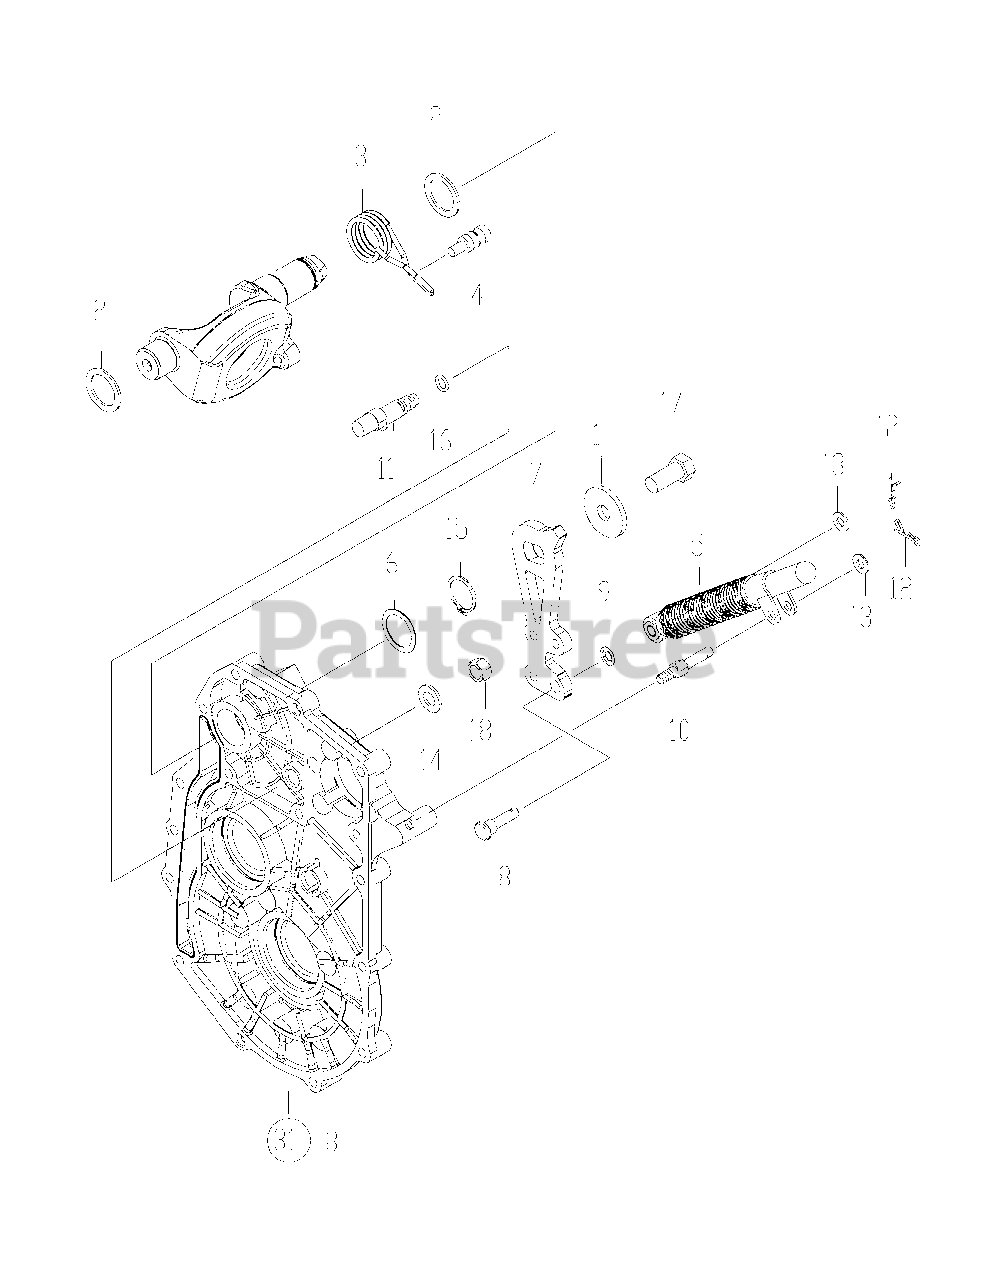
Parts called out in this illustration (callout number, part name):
1	WASHER, 44X14X4.5
2	WASHER, 28X38X2
3	SPRING, CENTERING
5	ABSORBER, SHOCK
6	WASHER, 29X35X1
8	PIN(CONTROL ARM
16	PACKING, P 10A
